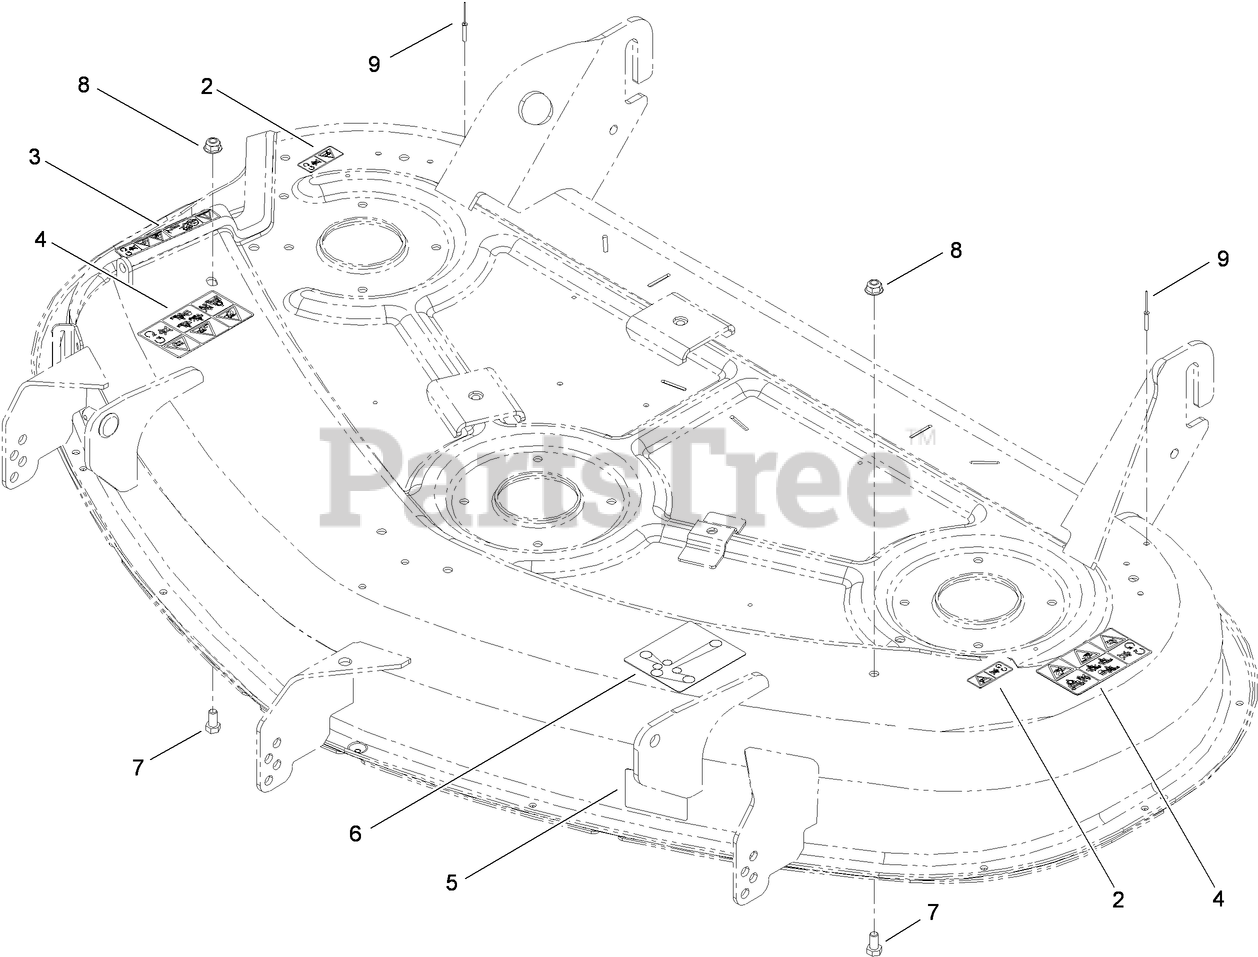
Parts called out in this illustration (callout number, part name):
2	DECAL-DANGER
3	DECAL-DANGER
4	DECAL-DANGER
5	DECAL-SCALP, ANTI
6	DECAL-ROUTING, BELT
7	SCREW-HH
8	NUT-HF, NI
9	RIVET-BLIND
